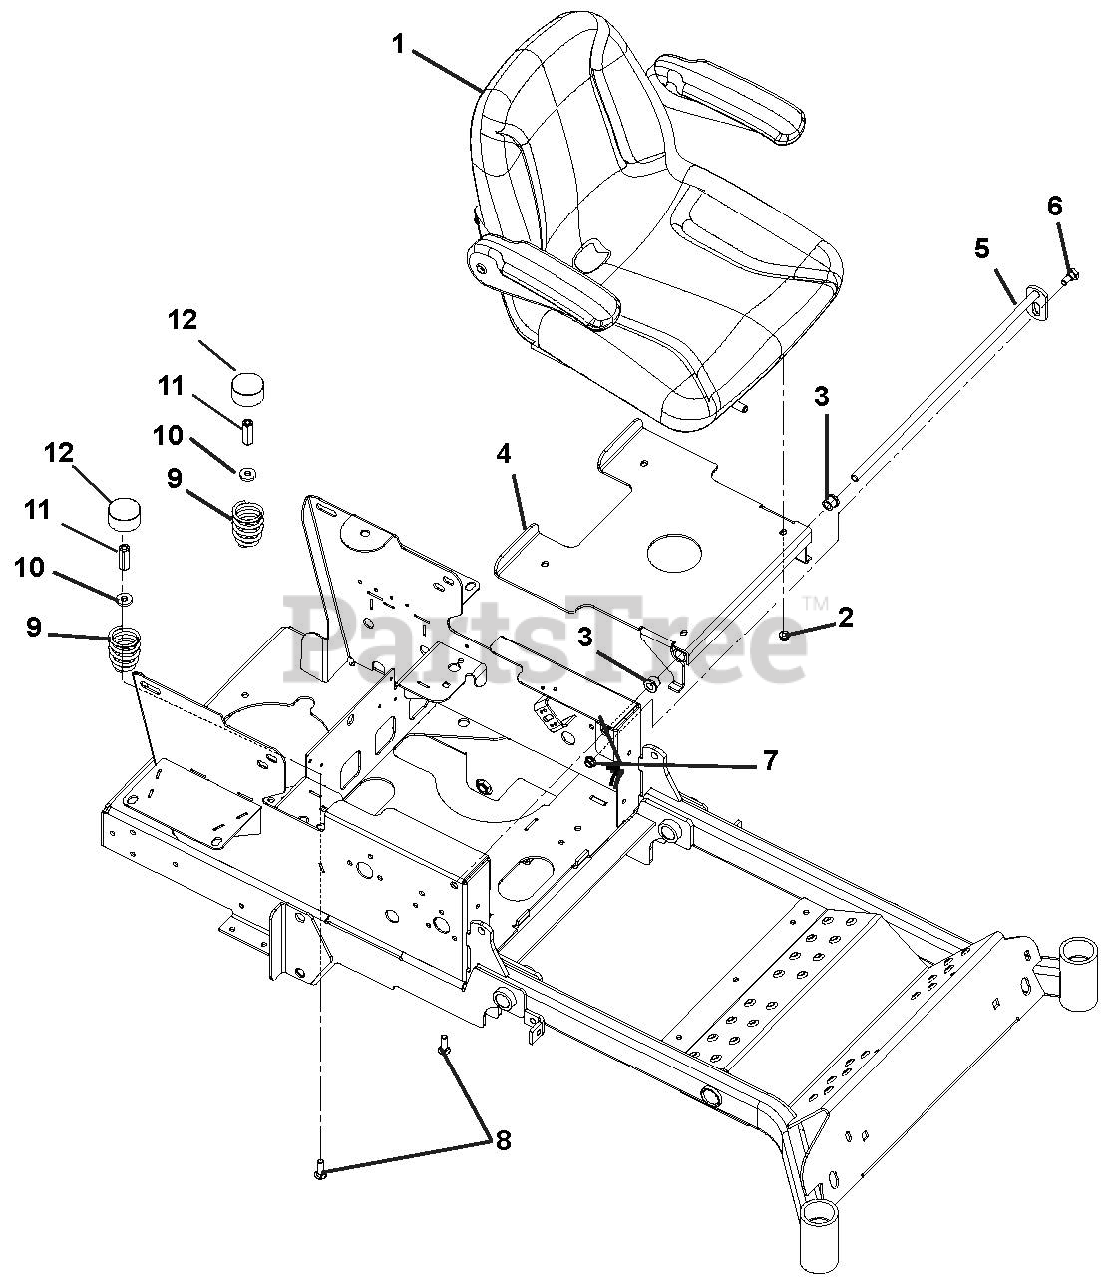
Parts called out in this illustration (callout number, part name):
1	Assembly, Seat with Armrests
2	Nut, Nyloc Flange 5/16-18
3	Bushing, Flange .515 x .750 x .745 x 1.00
4	Weldment, Seat Plate
5	Weldment, Seat Shaft
6	Bolt, Shoulder EP .38-16 x .30 Hex
7	Nut, .38-16 Nyloc Flange
8	Bolt, Round Head Square Neck .38-16 x 1.25 Grade 5
9	Spring, Seat
10	Washer, Flat-Steel .406 x 1.00 x .188
11	Nut, Coupling .375-16 x 1.75
